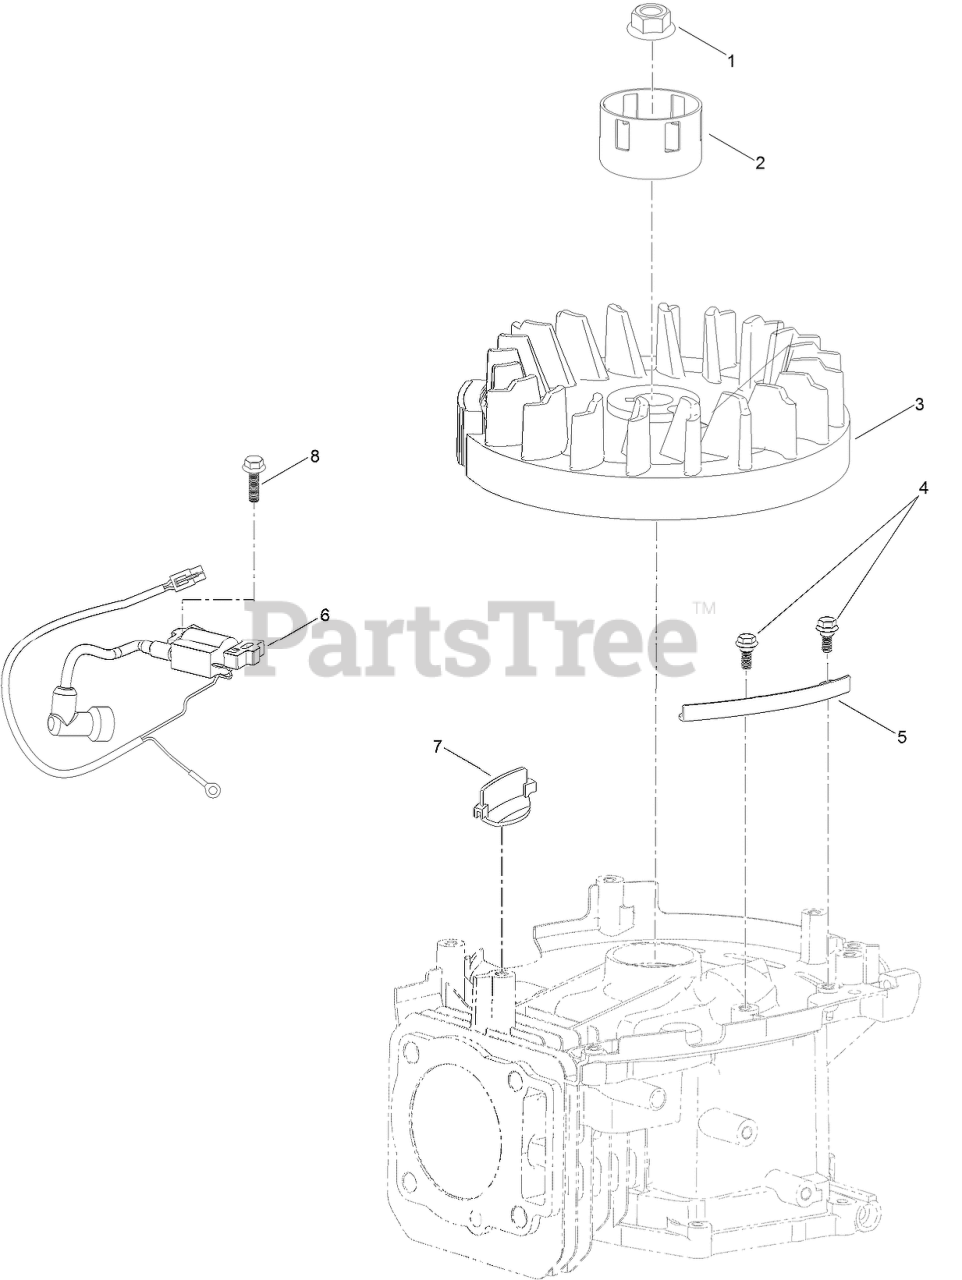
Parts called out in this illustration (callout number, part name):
1	NUT-FLANGE
2	CUP-STARTER
3	FLYWHEEL
4	SCREW-SHOULDER, HHF
5	GUARD-FLYWHEEL
6	COIL-IGNITION
7	GUARD-FLYWHEEL
8	SCREW-HHF
